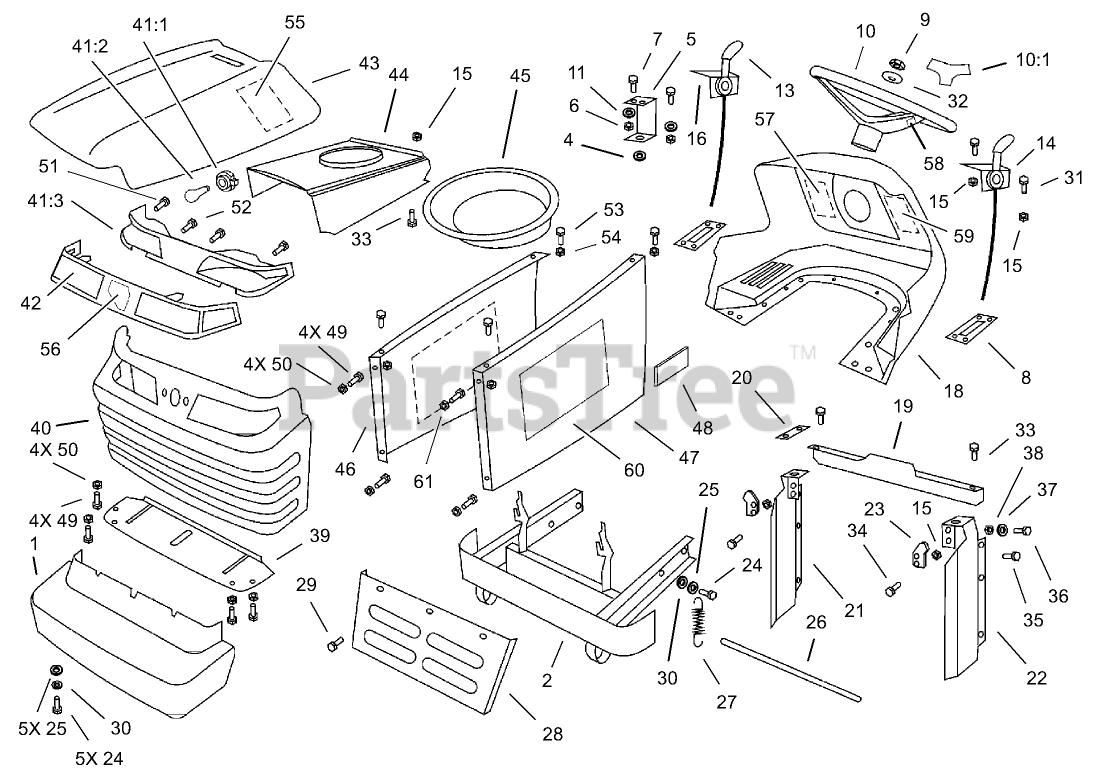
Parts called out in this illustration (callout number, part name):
1	COVER-BUMPER
2	BUMPER
4	BUSHING
5	HOLDER-TANK, FUEL
6	NUT-LOCK
9	NUT-LOCK
10	WHEEL-STEERING
10:1	COVER-WHEEL, STEERING
11	WASHER-PLAIN
14	CONTROL-CHOKE (TWIN)
15	NUT-LOCK
16	CONTROL-THROTTLE (TWIN)
18	PANEL-DASH
20	BRACKET
21	PANEL-RIGHT
22	PANEL-LEFT
23	LATCH-HOOD
24	SCREW-HH
25	WASHER-PLAIN
26	BAR-SAFETY
27	SPRING-HOOD
28	SHIELD-HEAT
29	SCREW-TAP
30	WASHER-LOCK, SPRING
32	Washer
37	WASHER
38	NUT-HEX
39	BRACKET
41	BULB
41:1	SOCKET-LIGHT
41:2	BULB
41:3	REFLECTOR-LIGHT
42	LENS - HEADLIGHT
43	HOOD-TOP
44	HOOD - BAFFLE
45	PLENNUM-AIR
46	SIDE-HOOD, RH
47	SIDE-HOOD, LH
48	FOAM-SIDEPANEL
50	NUT-HEX
51	SCREW-PLASTITE
53	SCREW-HWH
55	FOAM-HOOD
56	EMBLEM-HORSEHEAD
57	DECAL
58	DECAL
59	DECAL-CHOKE/PTO
60	DECAL-HOOD, LH
61	DECAL-HOOD, RH
